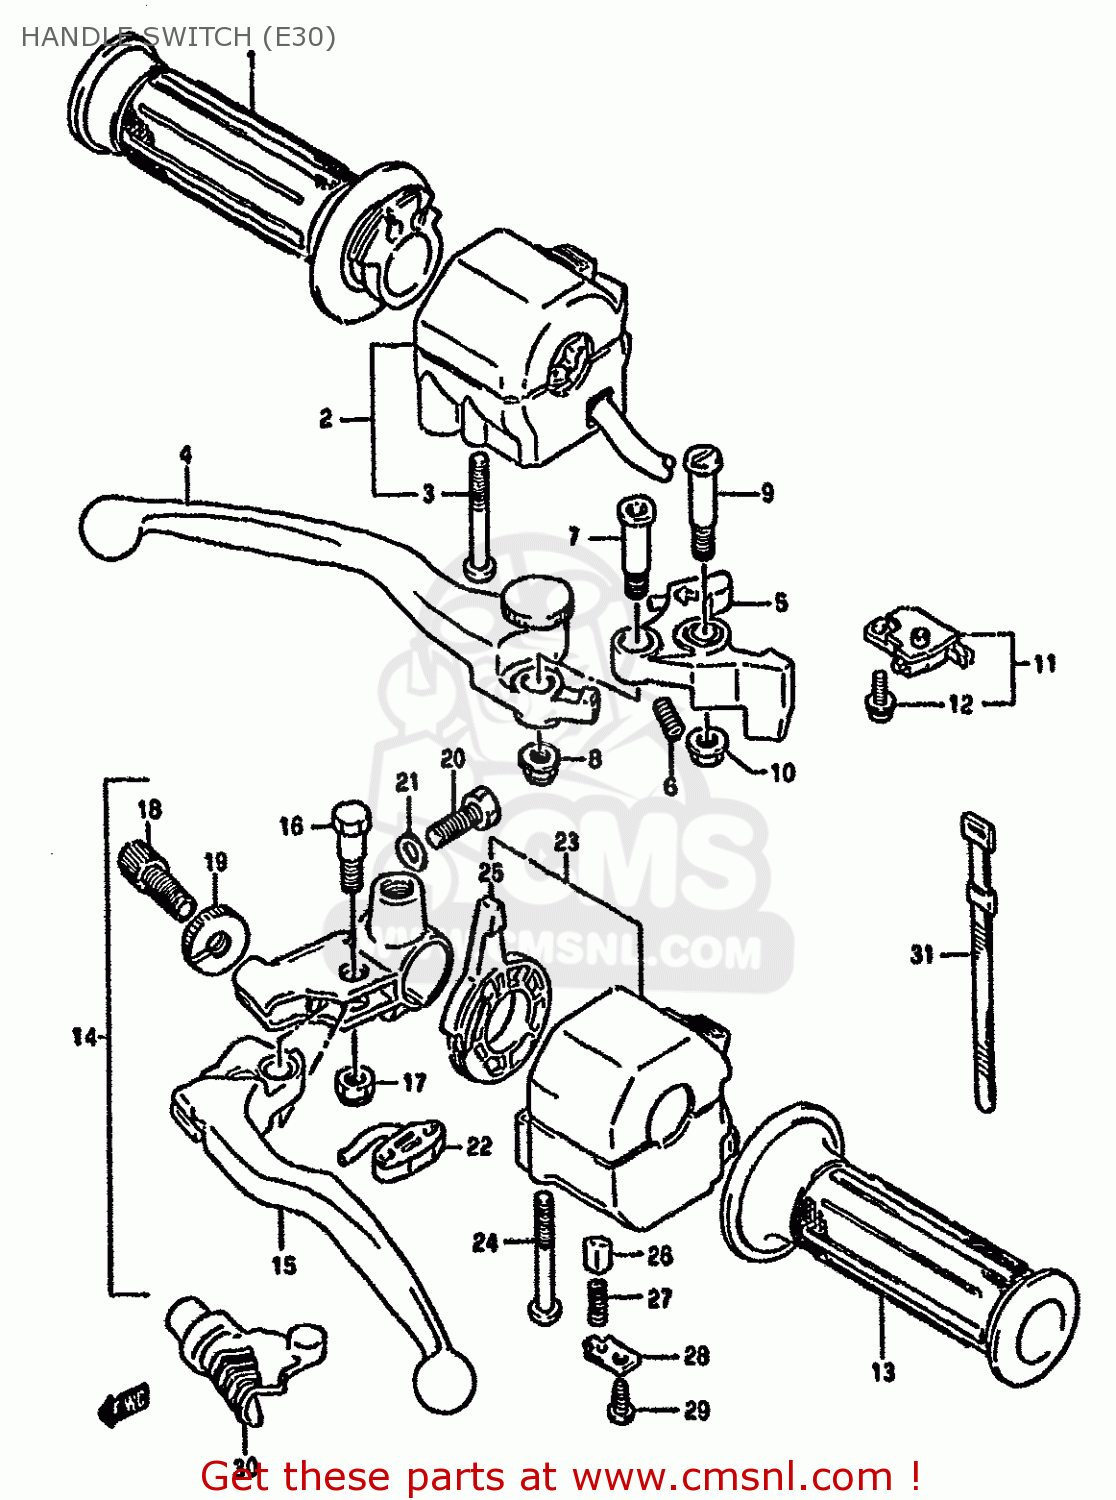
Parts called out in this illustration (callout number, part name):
1	GRIP,THROTTLE
2	SWITCH ASSEMBLY,HANDLE,RIGHT
3	SCREW, 5X45
4	LEVER,ADJUST
5	KNOCKER
6	SPRING
7	BOLT,LEVER
8	NUT
9	BOLT,LEVER PIVOT
10	NUT 6MM
11	SWITCH ASSEMBLY,STOP
12	SCREW
13	GRIP,L
14	LEVER ASSEMBLY,CLUTCH
15	LEVER,CLUTCH
16	BOLT,LEVER
17	NUT
18	ADJUSTER,CABLE
19	NUT,CABLE ADJUSTER
20	BOLT
21	WASHER
22	SWITCH ASSEMBLY,CLUTCH
23	SWITCH ASSEMBLY,HANDLE,LEFT
24	SCREW, 5X45
25	LEVER,CHOKE
26	PIECE,SLIDE
27	SPRING
28	PLATE
29	SCREW
30	COVER,CLUTCH LEVER
31	CLAMP(L:120)
